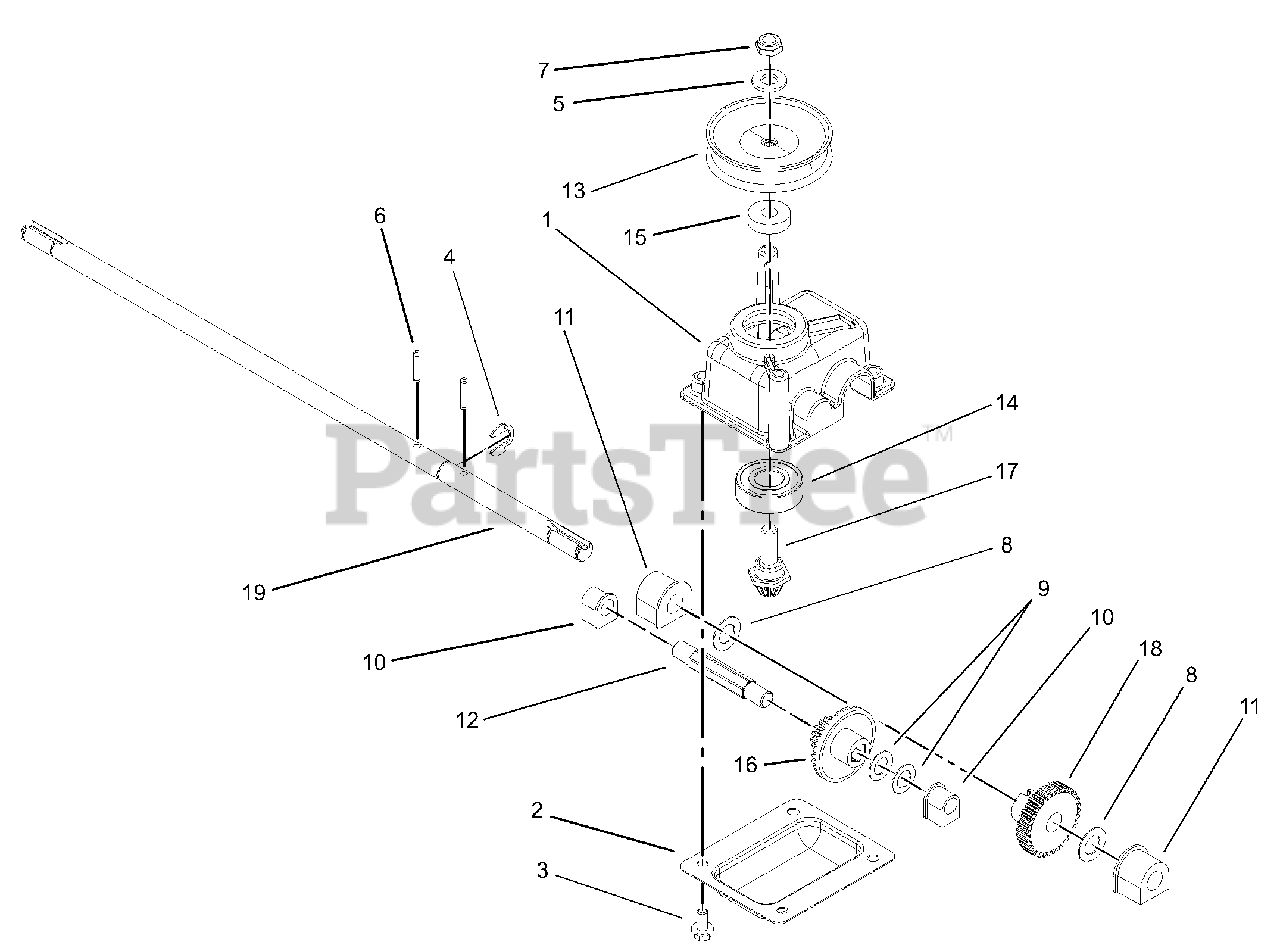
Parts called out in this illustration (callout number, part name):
1	Case-Gear
2	Cover-Case, Gear
3	Screw-HWH
4	Ring-Retaining
5	Washer-Flat
6	Pin-Groove
7	Nut-Lock, NI
9	Washer-Thrust
12	Shaft-Intermediate
13	Half-Pulley
14	Bearing-Ball
16	Gear-15t Spur, 37t Bevel
17	Gear-Pinion, Bevel
19	Shaft-Output
